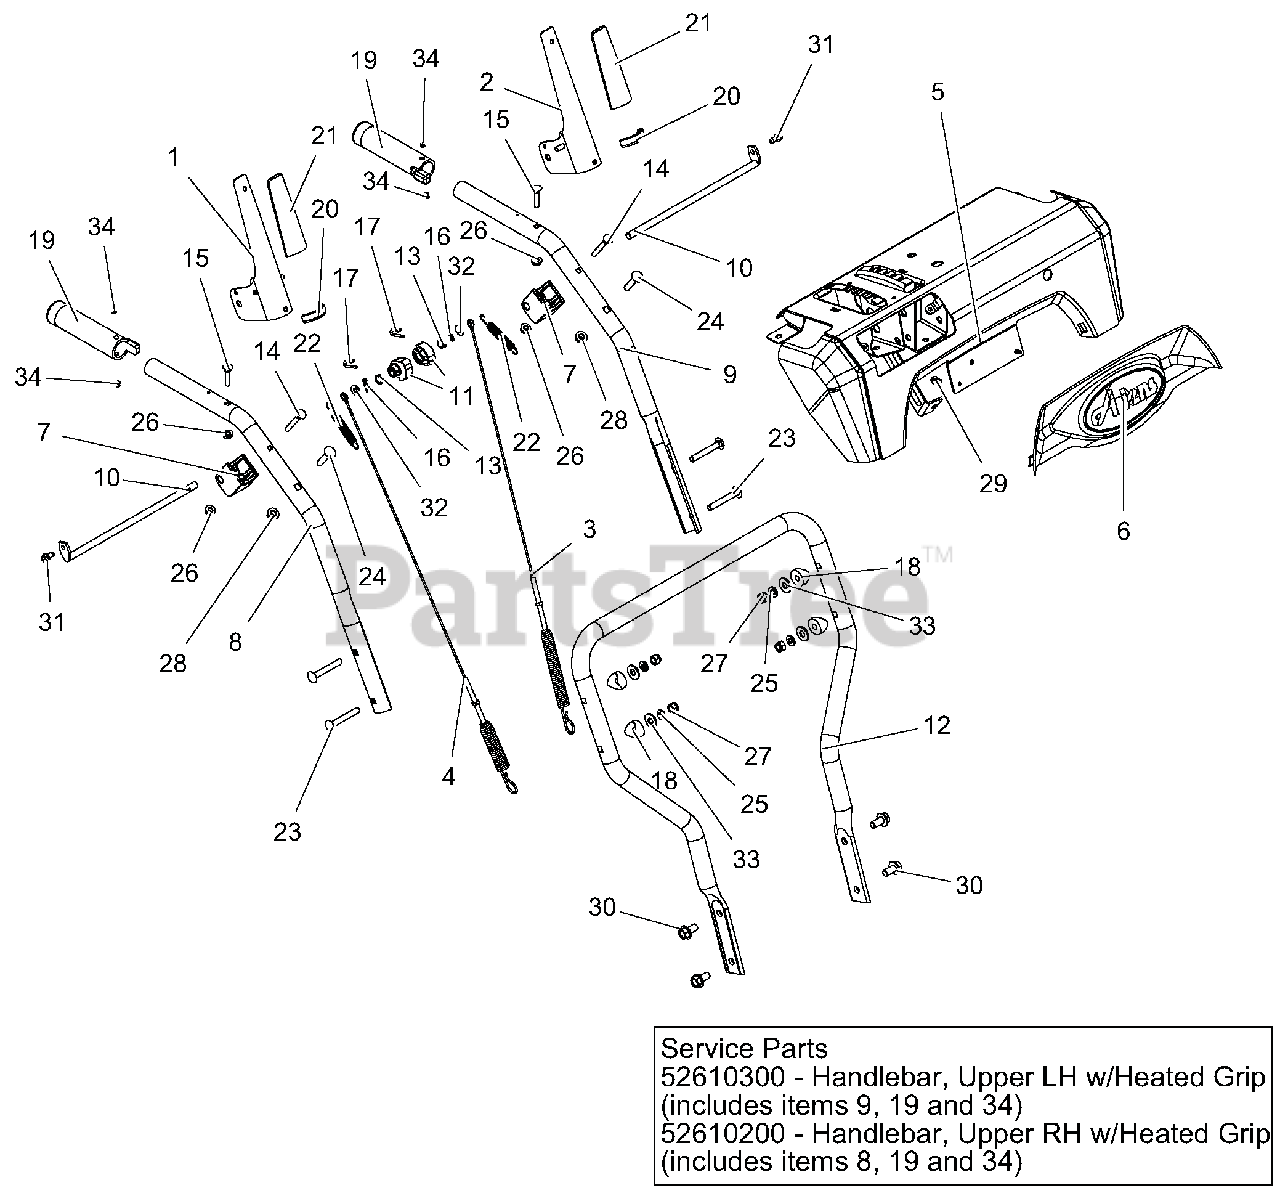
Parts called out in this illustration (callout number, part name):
1	LEVER, CLUTCH-RH
2	LEVER, CLUTCH-LH
3	CABLE, UPPER TRACTION
4	CABLE, AUGER (DELUXE & PRO)
5	CONTROL PANEL W/DECAL HW,ID,AD
6	DASH BEZEL, ARIENS LOGO - PRO
7	BLOCK, CLUTCH PADDLE
8	HANDLEBAR, UPPER - RH
9	HANDLEBAR, UPPER - LH
10	ROD, PADDLE MOUNT - PRO
11	CAM, INTERLOCK
12	HANDLEBAR, LOWER - DELUXE
13	BUSHING, POLYLINER-.38 SNAPIN
14	BLT-RDHDXLSQNK .25-20X2.0 G5YZ
15	BLT-RDHDXLSQNK.25-20X1.25 G5ZC
16	PIN-HAIR INT .06X.18X.77
17	PIN, SPRING CLIP
18	SPACER, HANDLEBAR
19	HEATED GRIP, MAGURA
20	EDGING, CLUTCH PADDLE - 2.00"
21	CLUTCH PADDLE SLEEVE - GRAY
22	SPRING, EXTENSION
23	@BLT-RDHDSQNK .31-18X2.25 G5YZ
24	@BLT-RDHDSQNK .31-18X1.50 G5YZ
25	WSHR-LK .312X.097 HVY YWZC
26	@NUT-LK-CTR-FLG .25-20 YWZC
27	@NUT-LK-NYL .312-18 YWZC
28	@NUT-LK-TOP-FLG .31-18 YWZC
29	SCR-TAP #10X.50 BOSS INDHXHD
30	BLT-SERHFWH .38-16X.75 YWZC
31	SCR-TAP .25-20X.50 HWH TR YWZ
32	@WSHR-FL-STL.281X.62X.065 YWZC
33	@WSHR-FL-STL.38X.875X.083 YWZC
34	RVT-POP #43 .125X.313 STL ZINC
